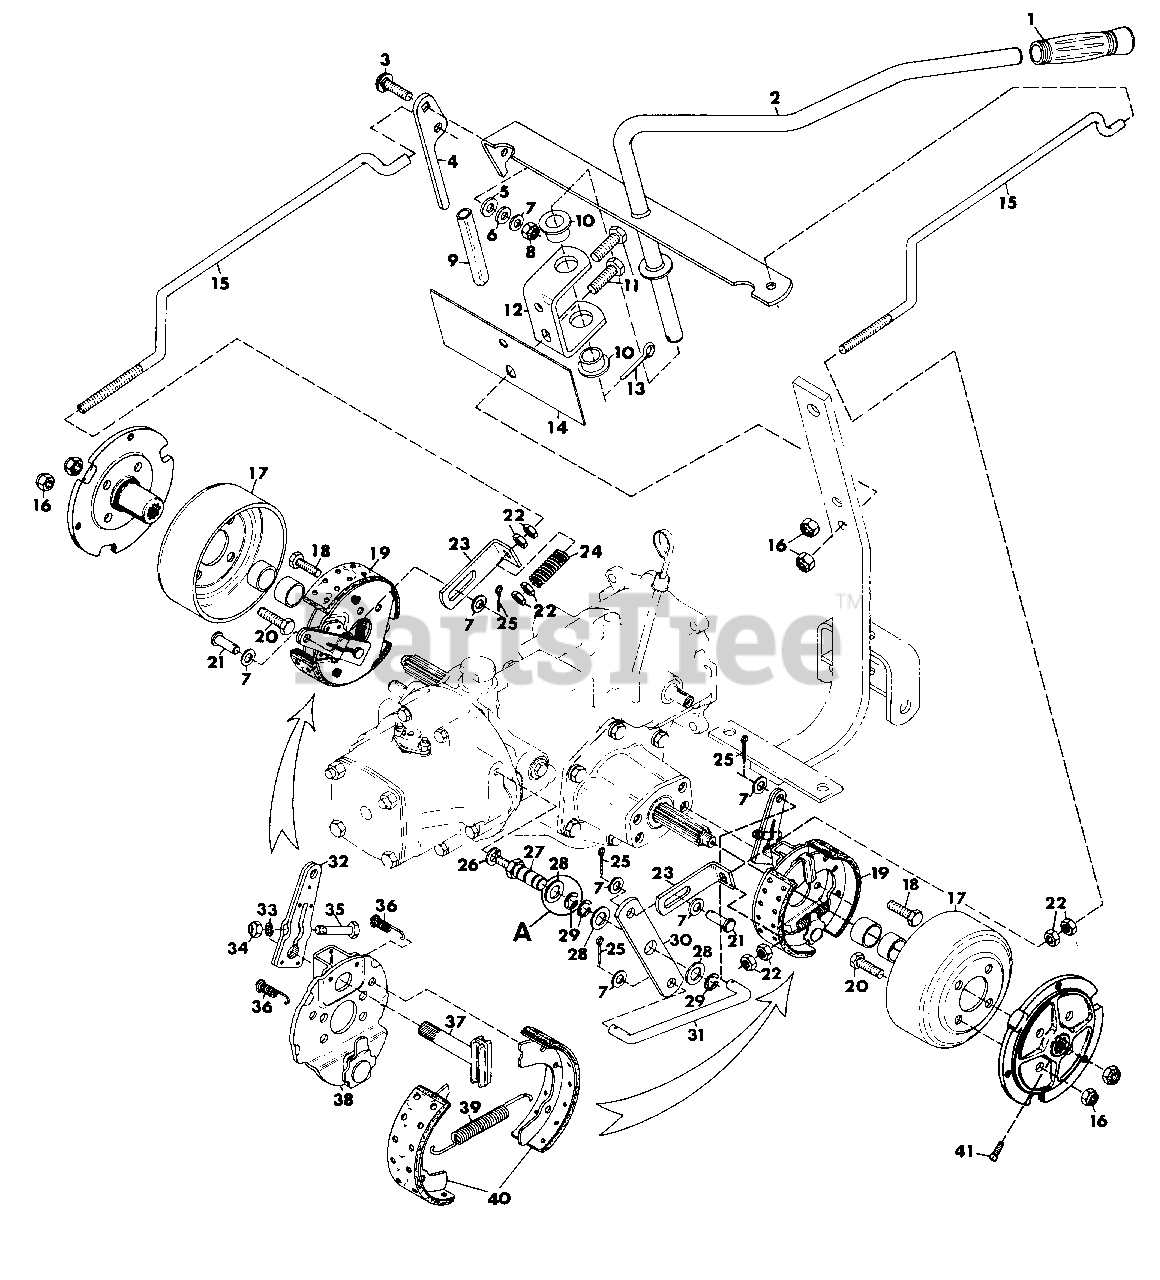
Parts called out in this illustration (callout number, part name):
1	GRIP, HAND
2	WELDMENT, BRAKE HANDLE
4	HANDLE, PARKING BRAKE
5	WASHER, NYLON .375X.75X.060
6	WASHER, RUBBER .375X.750X.125
7	WASHER, FLAT .406X.812X.065
8	NUT, LOCK 3/8-16
9	GRIP, PARKING BRAKE HANDLE
10	BUSHING, PIVOT
11	BOLT, HEX 1/2-13X1.75
12	SUPPORT, BRAKE HANDLE
13	PIN, COTTER .188X1.500
14	PLATE, INSTRUCTION
15	ROD, BRAKE
16	NUT, LOCK 1/2-13
17	DRUM, 7X1.75
18	BOLT, HEX 3/8-16X.875
19	BRAKE, 7X1.75 MECHANICAL
20	BOLT, HEX 1/2-13X1.375
21	PIN, CLEVIS .375X.750
22	NUT, JAM 3/8-16
23	BRACKET, ADJUSTMENT
24	SPRING, COMPRESSION
25	PIN, COTTER .09X.75
26	WASHER, LOCK 3/8 REG.
27	STUD, PIVOT
28	WASHER, FLAT .656X1.312X.095
29	E-RING, .625 SHAFT
30	PLATE, PIVOT
31	ROD, BRAKE LINK
32	ARM, CAM LEVER
33	WASHER, LOCK 5/16 REG.
34	NUT, HEX 5/16-24
35	BOLT, HEX 5/16-24X1.75
36	SPRING, SHOE RETAINING
37	CAM, BRAKE
38	PLATE, BACK
39	SPRING, SHOE RETURN
40	KIT, BRAKE SHOE
41	SCREW, SET 7/16-14X.75 CPSH
